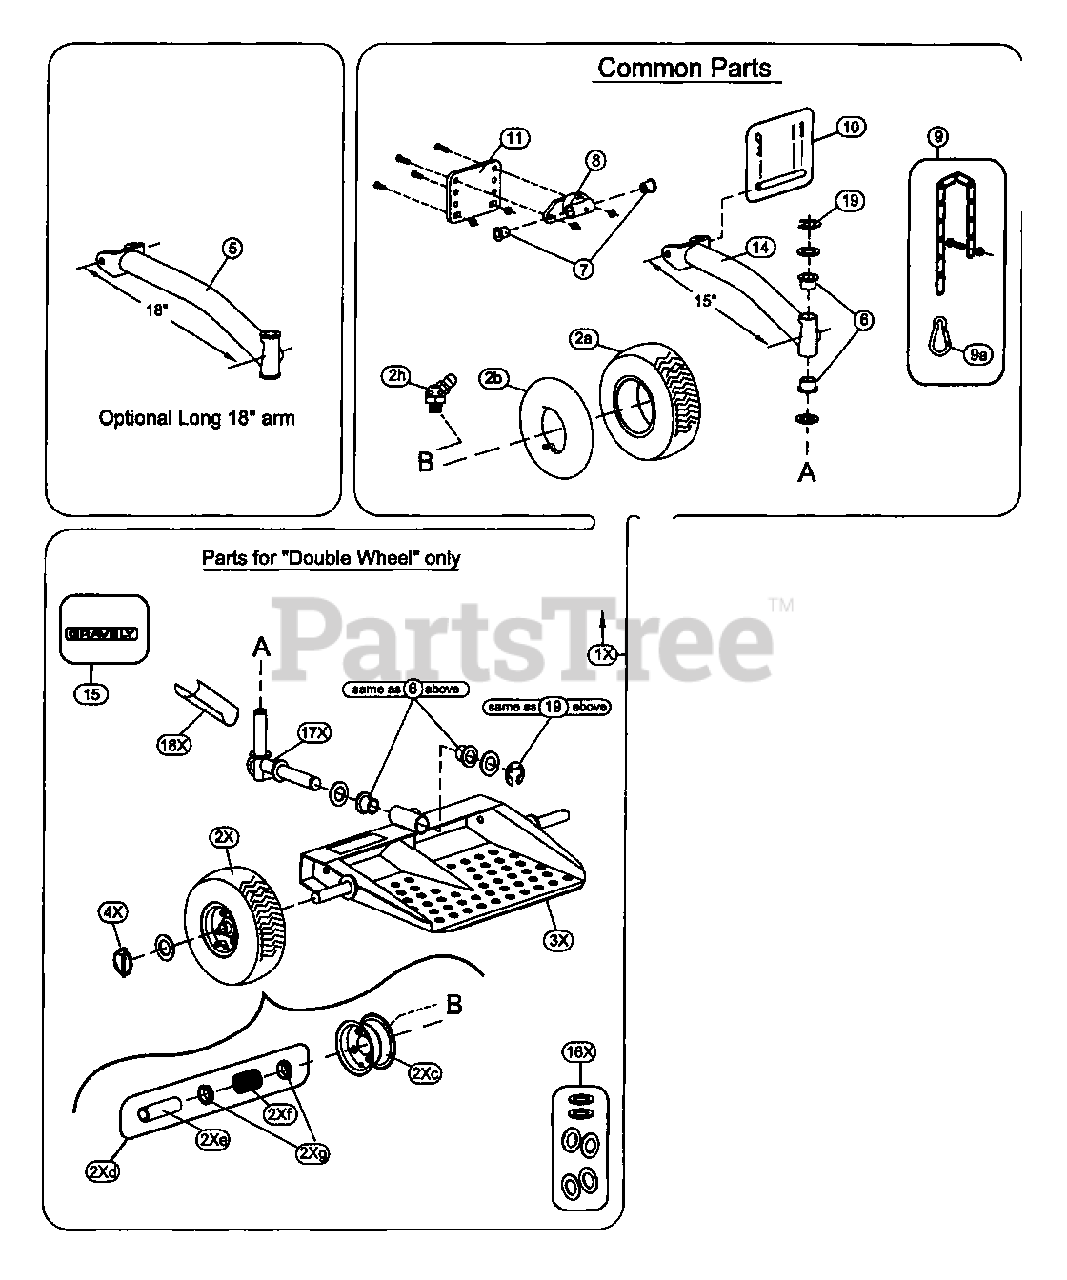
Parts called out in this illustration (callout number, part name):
1X	SULKY, Double Wheel w/15" arm
2X	Wheel Assy., w/offset hub & spanner
3X	Foot Platform, Double Wheel (w/decals,bushings,zerk)
4X	Linch Pin
5	Arm, 18" (w/bushings & grease fitting)
6	Bronze Bushing pivot(s)
7	Bronze Bushing for hitch
8	Hitch (w/bushings & grease fitting)
9	Snap & Chain Kit
10	Clevis pin
11	Adapter plate
14	SHORT 15" arm (w/bushings)
15	Gravely Logo Decal
16X	Spacer kit
17X	Intermediate Pivot
18X	Protective cover
19	E Clip 7/8"
